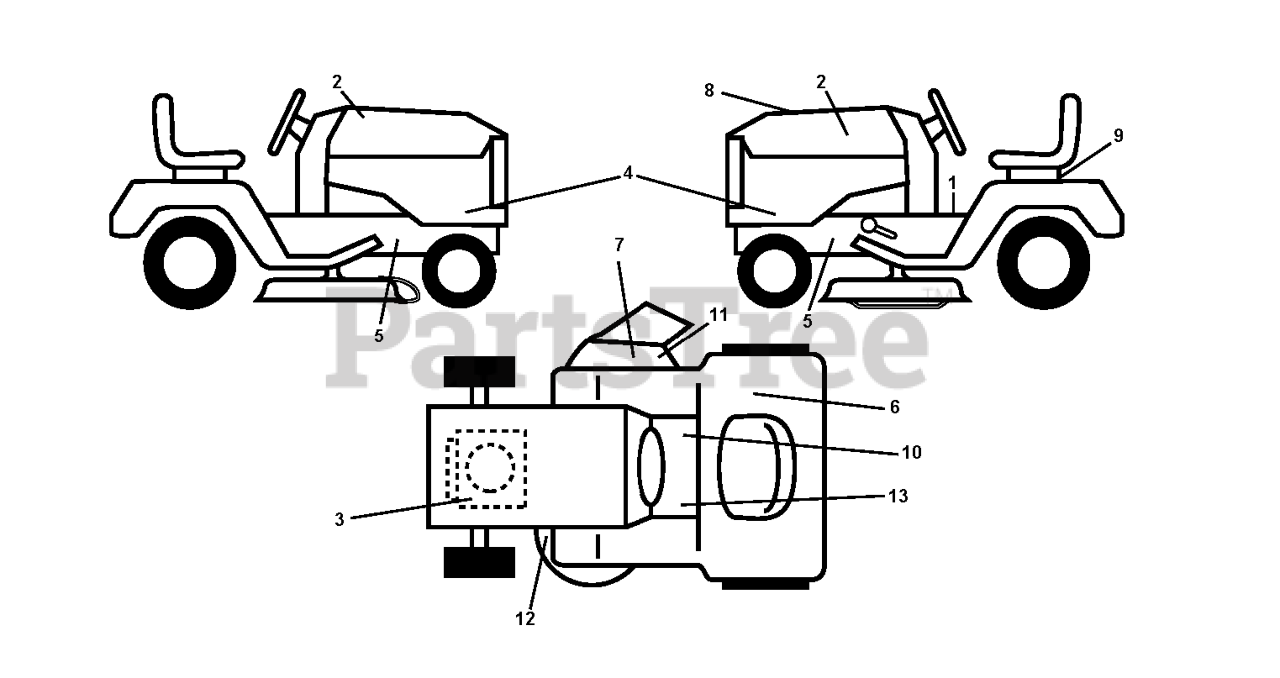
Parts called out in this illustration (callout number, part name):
1	LABEL
2	RP.DECAL.BADGE.170MM.TEXTLOGO
3	DECAL
6	Decal, Fender 100 DB/CE
7	DECAL.INTERNATIONL.CUTFINGER
9	DECAL BTRY SYMBOLS
10	DECAL PARK BRAKE
11	DECAL, DEFLECT WARNING
12	DECAL V BELT SCHEMATIC
13	DECAL
